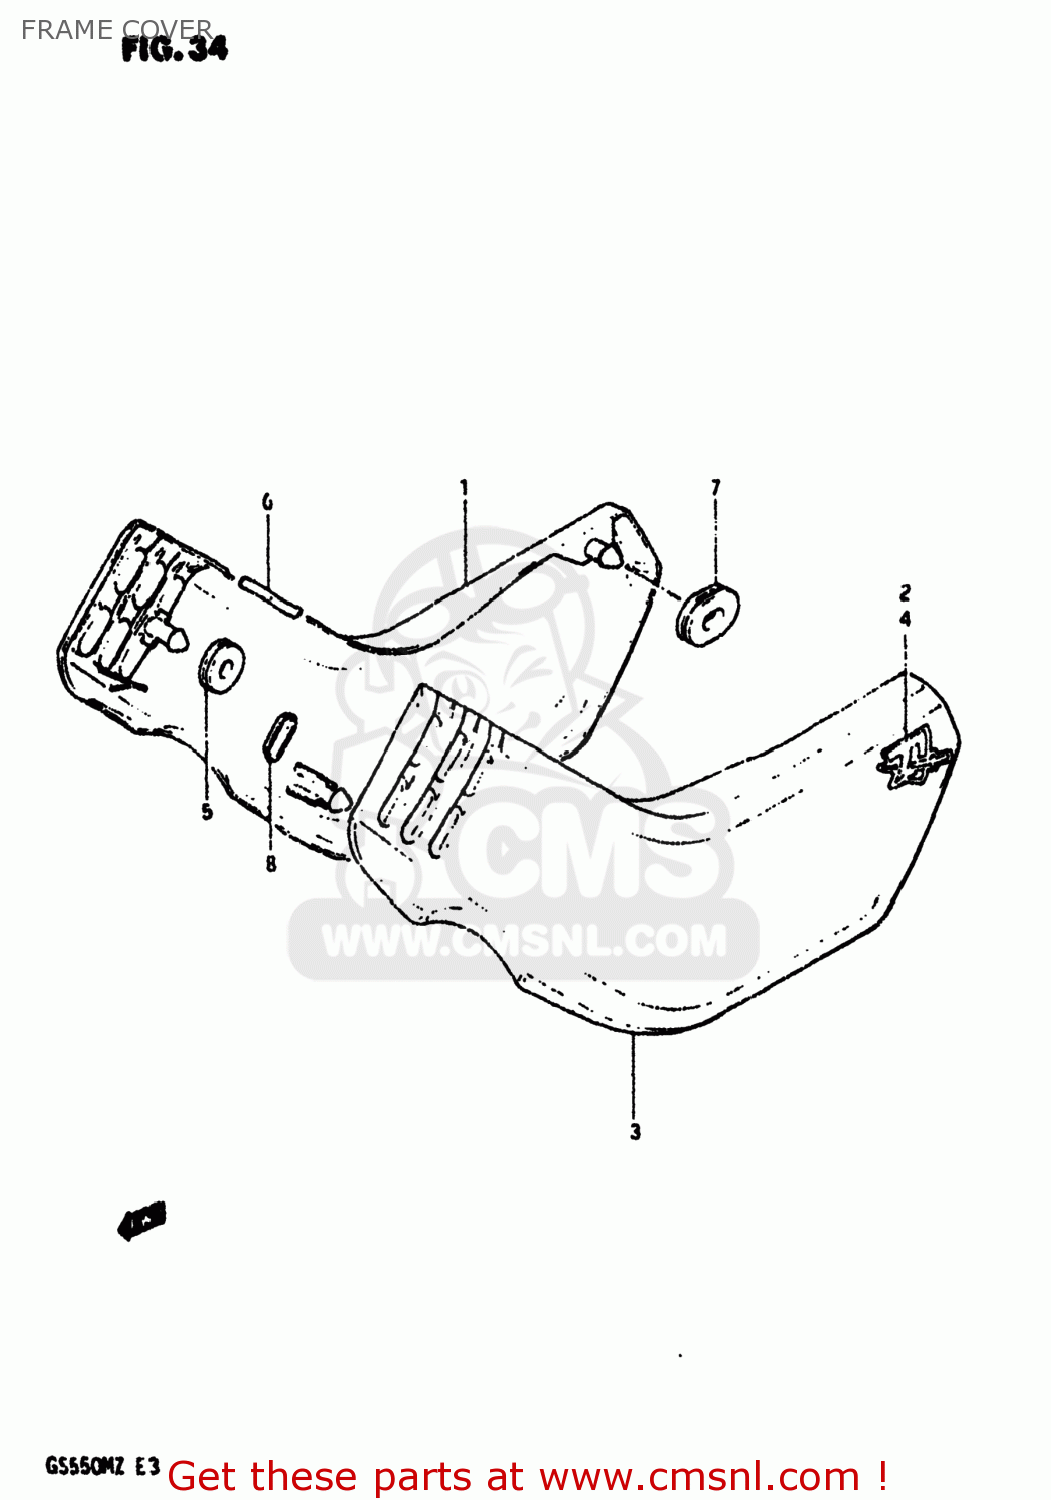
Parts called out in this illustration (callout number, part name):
1	COVER,FRAME,RIGHT
2	EMBLEM
3	COVER,FRAME,LEFT
4	EMBLEM
5	CUSHION
6	CUSHION
7	CUSHION
8	EMBLEM,FRAME COVER
